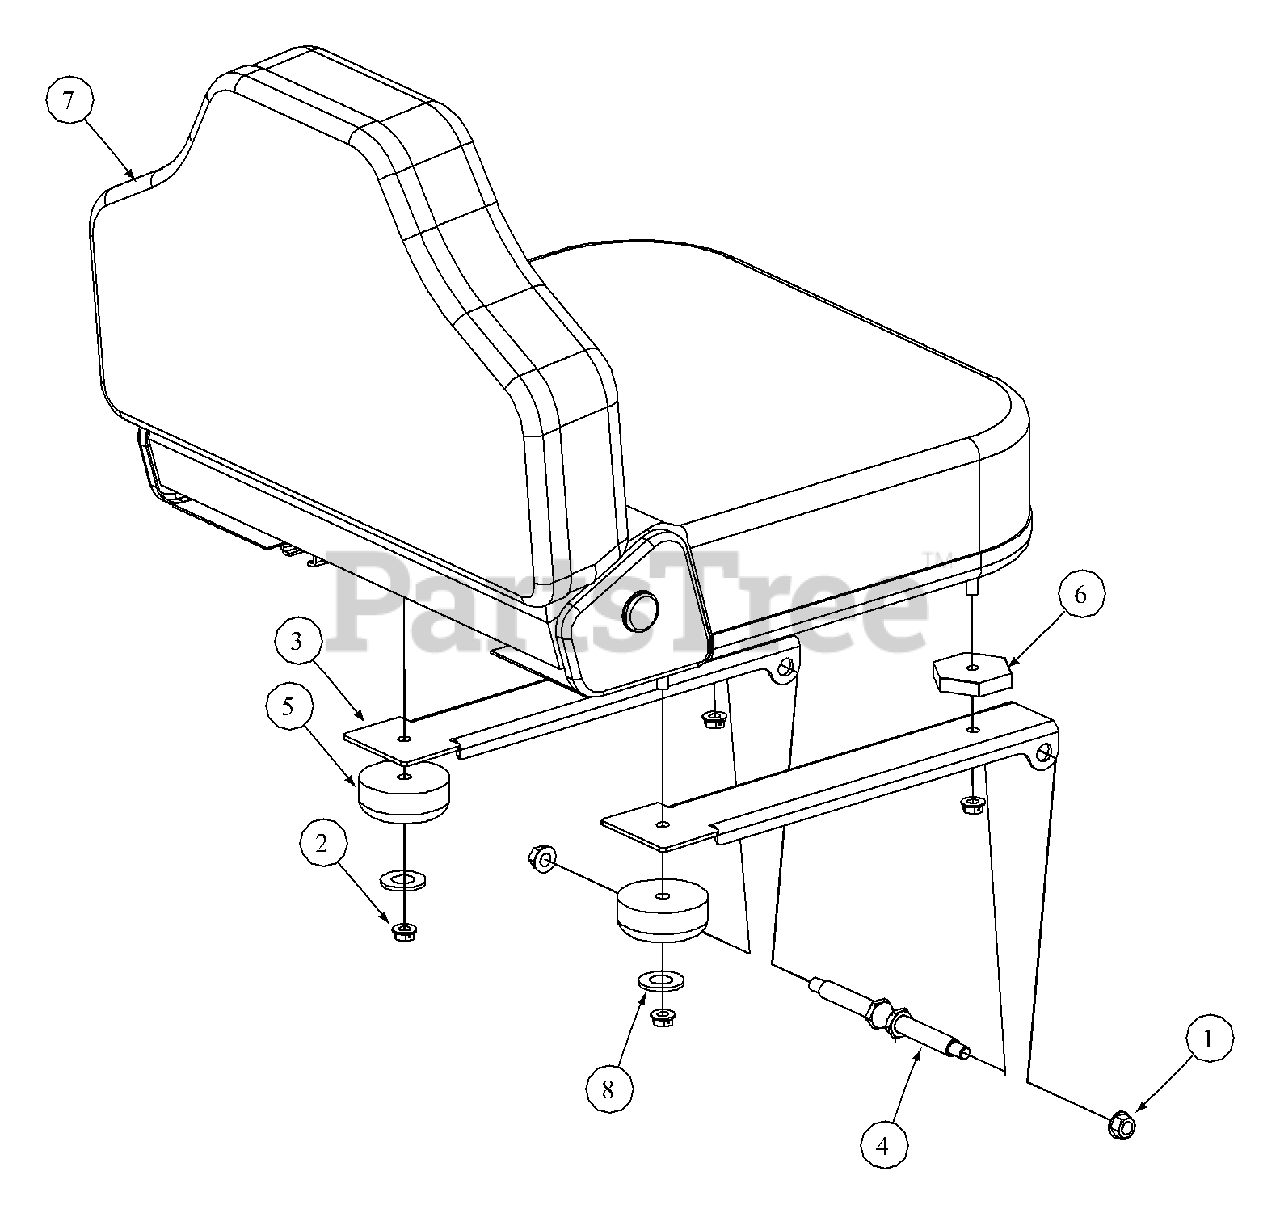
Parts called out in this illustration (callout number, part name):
1	Nut, Hex 3/8-16 Flange Lock
2	Lock Nut, Hex Flange, 5/16-18
3	Mounting Bracket, Seat
4	Shoulder Screw, .50x2.345, 3/8-16
5	Grommet, 2.5 OD x 1.0 Long
6	Spacer, 2.0 Hex x .41 Lg
7	Adjustable Seat, Black
8	Flat Washer, .406 ID, 1.00 OD, .105
